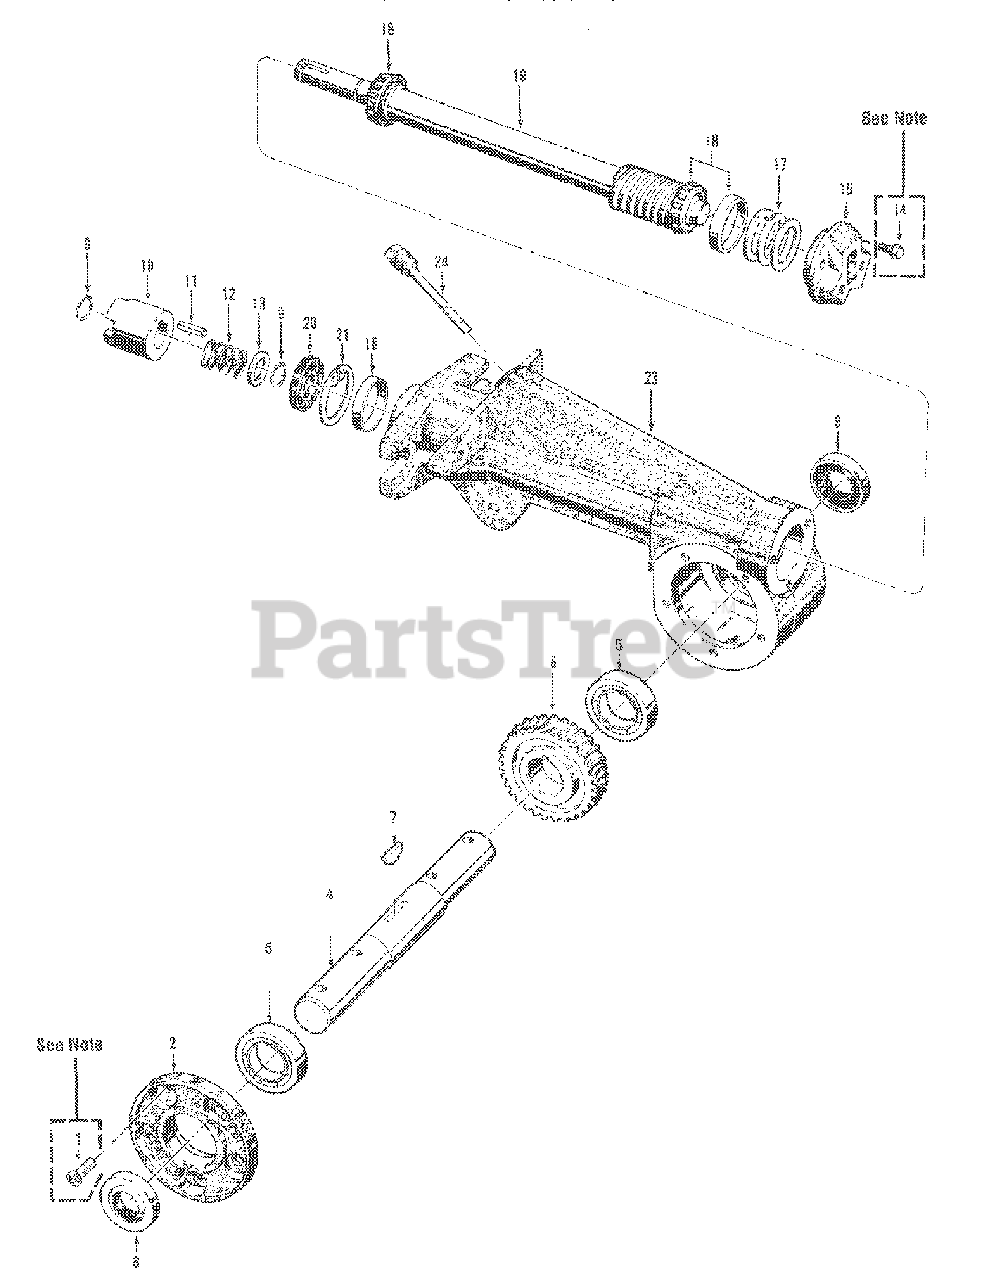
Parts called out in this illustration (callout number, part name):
1	Screw-self-sealing,1/4"-20
2	Cover-tiller housing
4	Shaft-tiller tine
5	Ball Bearing
6	Worm Gear-bronze, tiller tine shaft
7	Key-tiller tine shaft, woodruff key
8	Seal-oil, tiller tine shaft
9	Retaining Ring-external
10	Dog Clutch-tiller drive shaft
11	Key-3/16" x 1"
12	Spring-dog clutch]
13	Shim-dog clutch, 1/16"(.62")
14	Screw-self-sealing,1/4"-20 x 7/8
15	Cap-rear bearing
17	Shim-front bearing cap, .010" thick
17	Shim-same as above, .030" thick
17	Shim-same as above, .005" thick
17	Shim-same as above, .062 thick
18	Bearing & Race incl one bearing GW-9400 & onecup (race) GW-9401
19	Shaft-main tiller drive
20	Seal-oil, drive shaft,
21	Retaining Ring-internal
23	Housing-tiller attachment (Empty housing without shafts, gears, seals,dipsticks, etc.)
24	Dipstick-oil, tiller attachment
